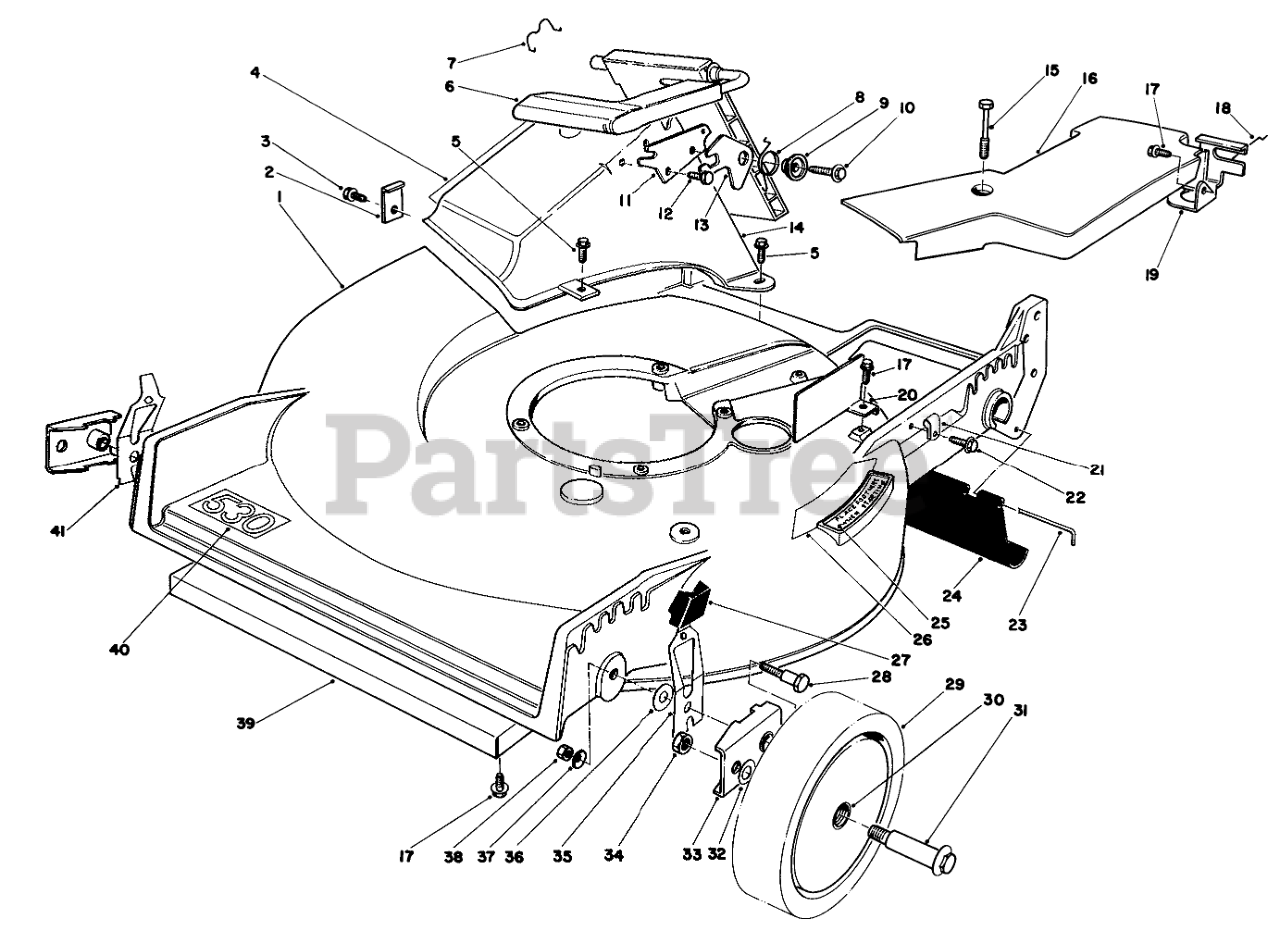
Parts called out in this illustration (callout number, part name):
1	21 SP RB HSG/DECAL
2	TUNNEL CLIP
3	SCREW
4	ATTENTION DECAL
5	SCREW-HWH
6	Discharge Door Assembly
7	DOOR RET SPRING
8	TORSION SPRING
9	DOOR SPACER
10	SCREW-HWH
11	DOOR LATCH PLATE
12	SCREW-PLASTITE
13	SAFETY LATCH
14	Tunnel Discharge
15	SCREW-HHFTF
16	Cover-Belt
17	SCREW-HWHTF
18	RETAINER-CABLE
19	Bracket-Traction Adj.
20	Shield-Muffler
21	CLAMP-CABLE
22	SCREW
23	ROD-SHIELD
24	SHIELD-TRAILING
25	STEP PAD DECAL
26	Decal-Place Foot Here
27	KNOB-ARM
28	PIVOT SCREW
29	Wheel & Tire Assy. (Incl. Ref. #30)
30	BUSHING
31	WHEEL BOLT
32	WASHER
33	HP PIVOT ARM ASM
34	NUT-LOCK
35	L. HP SPRING ARM ASM
36	WASHER-PIVOT
37	WASHER-BELLEVILLE
38	NUT-LOCK, NI
39	Shield-front
40	Decal-530
41	R HP SPRING ARM ASM
